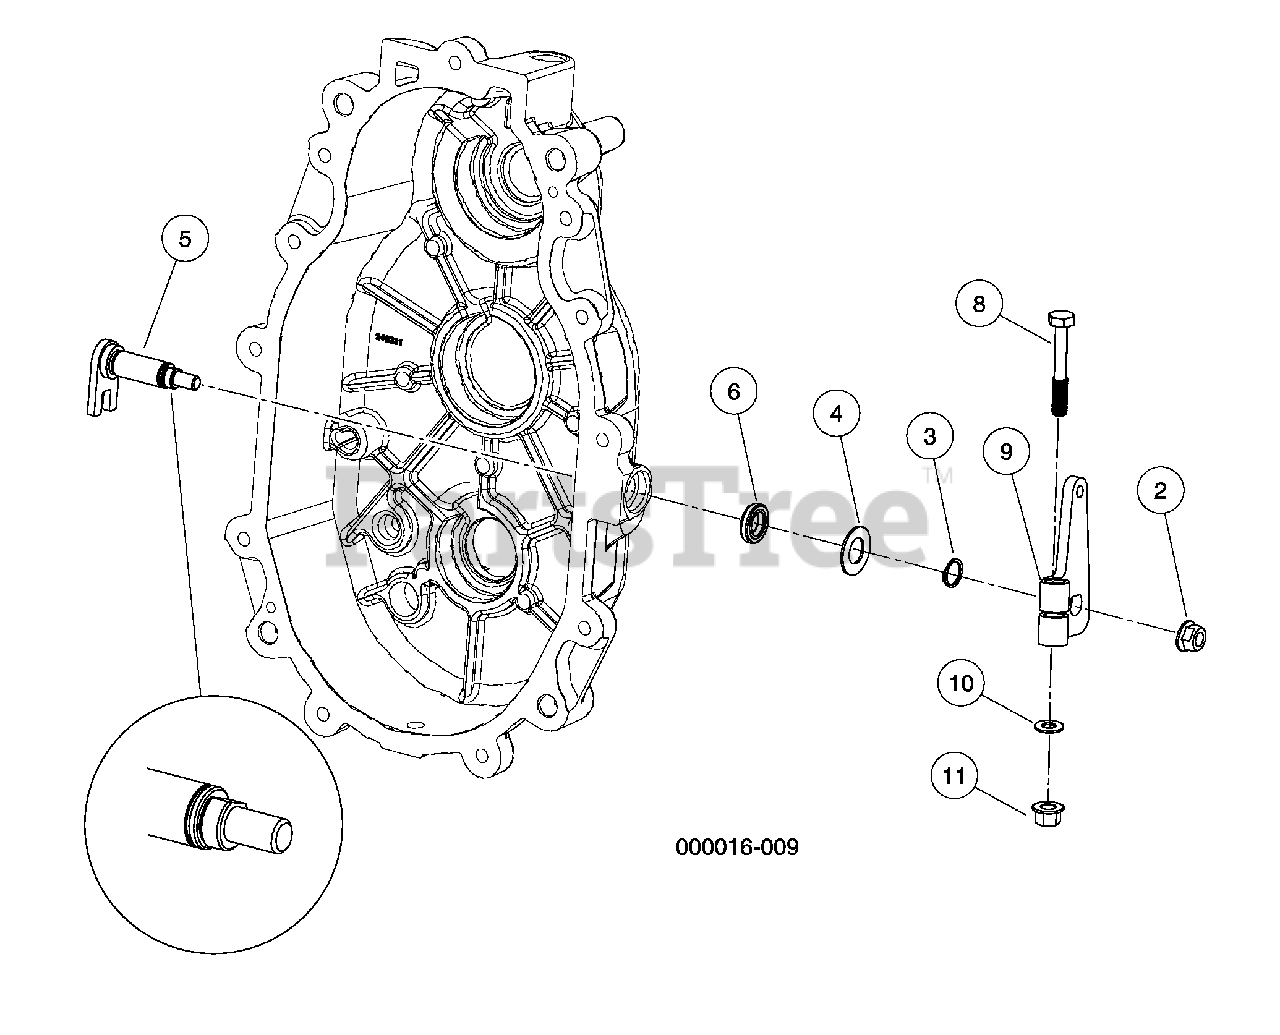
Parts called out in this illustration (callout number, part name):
1	Kit, Trans Shift Shaft Repair
2	Nut, Lock Hex, Nylon, 5/16-24
3	Ring, Retaining, External 9/16
4	Washer, Flat, .58 X 1.08 X .05
5	Weldment, Shift, Shaft
6	Seal, Dul Lip, .88 X .56 X .19
7	Kit, Bellcrank, D Shape, Clamp
8	Bolt, 3/8-16 X 2.00 Hex Head.
9	Asm, Bellcrank, D Shape, Clamp
10	Washer, 3/8 Type A Flat
11	Locknut, 3/8-16 Hex
